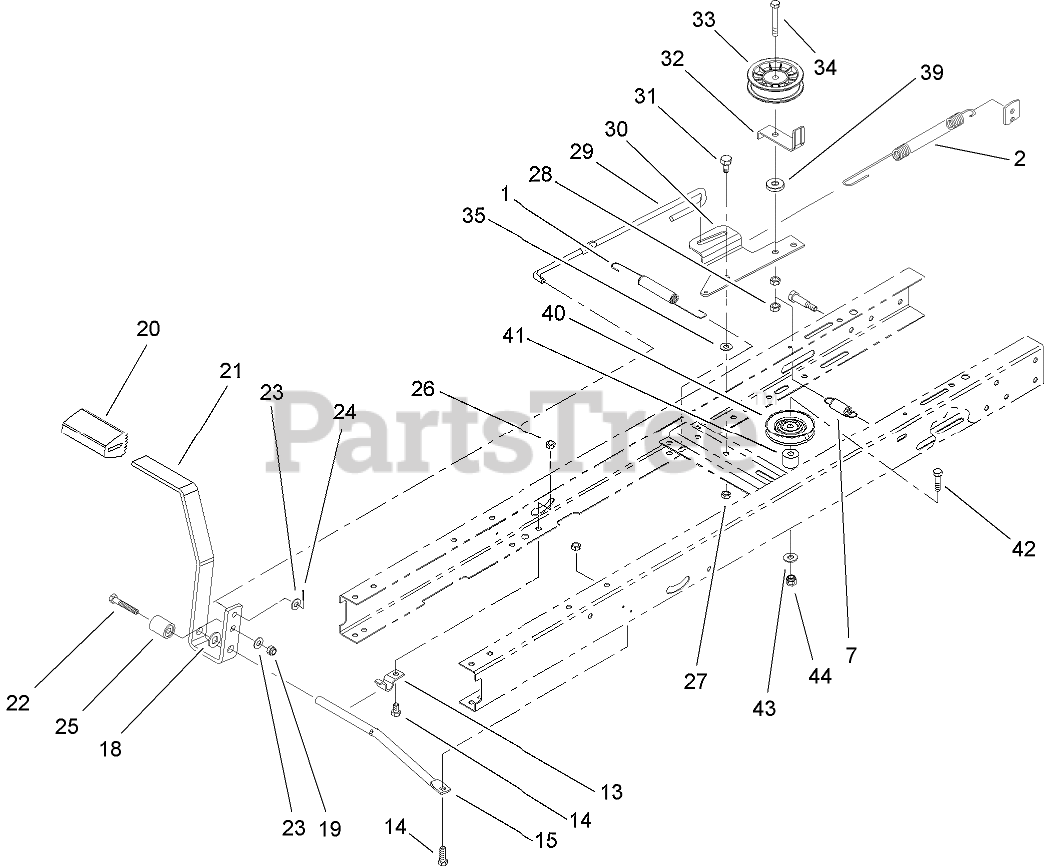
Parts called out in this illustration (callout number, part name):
1	SPRING-EXTENSION
2	SPRING-EXTENSION
7	SPRING-EXTENSION
13	CLAMP-PIVOT, SHIFT
14	SCREW-HH
15	ROD-PIVOT, PEDAL
18	WASHER-FLAT
19	NUT-LOCK, NI
20	PAD-PEDAL
21	PEDAL-CLUTCH/BRAKE, HYDRO
22	SCREW-HH
23	WASHER-PLAIN
24	PIN-COTTER
25	SPACER
26	NUT-LOCK, NI
27	NUT-LOCK, NI
28	NUT-LOCK, NI
29	ROD-CLUTCH/BRAKE
30	ARM-IDLER
31	BOLT-SHOULDER
32	GUIDE-IDLER, BELT
33	PULLEY-IDLER
34	SCREW-HH
35	WASHER-PIVOT
39	WASHER
40	PULLEY-IDLER
41	SPACER
42	SCREW-HH
43	WASHER-FLAT
44	NUT-LOCK, NI
